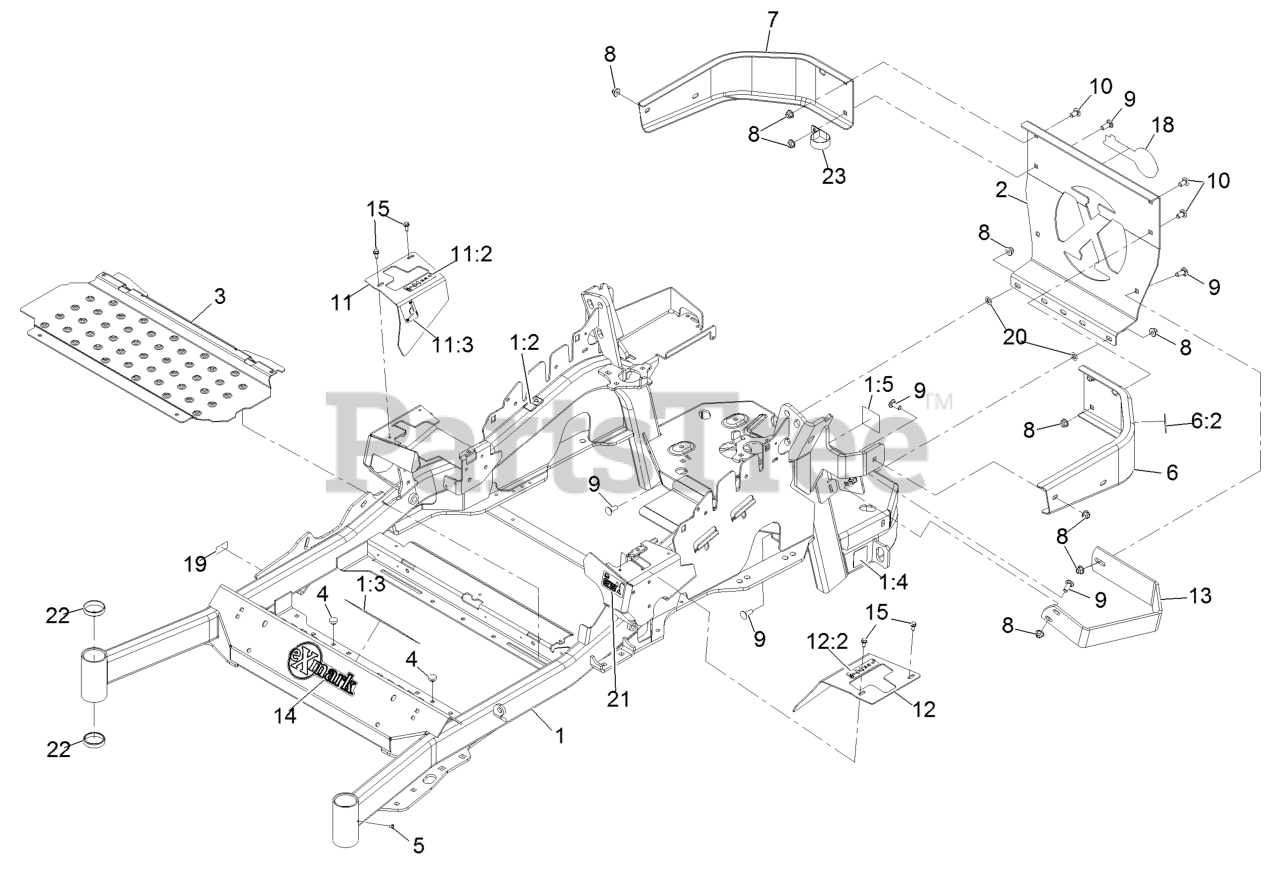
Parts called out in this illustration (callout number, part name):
1	MAINFRAME ASM
1:2	DECAL-WARNING
1:3	DECAL-DANGER
1:4	DECAL-HAZARD, PINCHED FINGER
1:5	DECAL-SPARK ARRESTER
2	PLATE,REAR GUARD
6	LH BUMPER ASM
6:2	DECAL-WARNING
7	BUMPER-RH
8	NUT-HF, NI
9	SCREW-CARR
10	SCREW-CARR
11	RH MOTION CONTROL COVER ASM
11:2	DECAL-CONTROL, MOTION
11:3	DECAL-PARK BRAKE, CE
12	LH MOTION CONTROL COVER ASM
12:2	DECAL-CONTROL, MOTION
13	GUARD-MUFFLER
14	DECAL-EXMARK LOGO
15	SCREW-HWH
18	DECAL-EXMARK LOGO
19	Decal-Patent Ttco.Com
20	NUT-PUSH
21	DECAL-FUEL FILL, CE
22	CUP-BEARING
23	CLAMP-R
